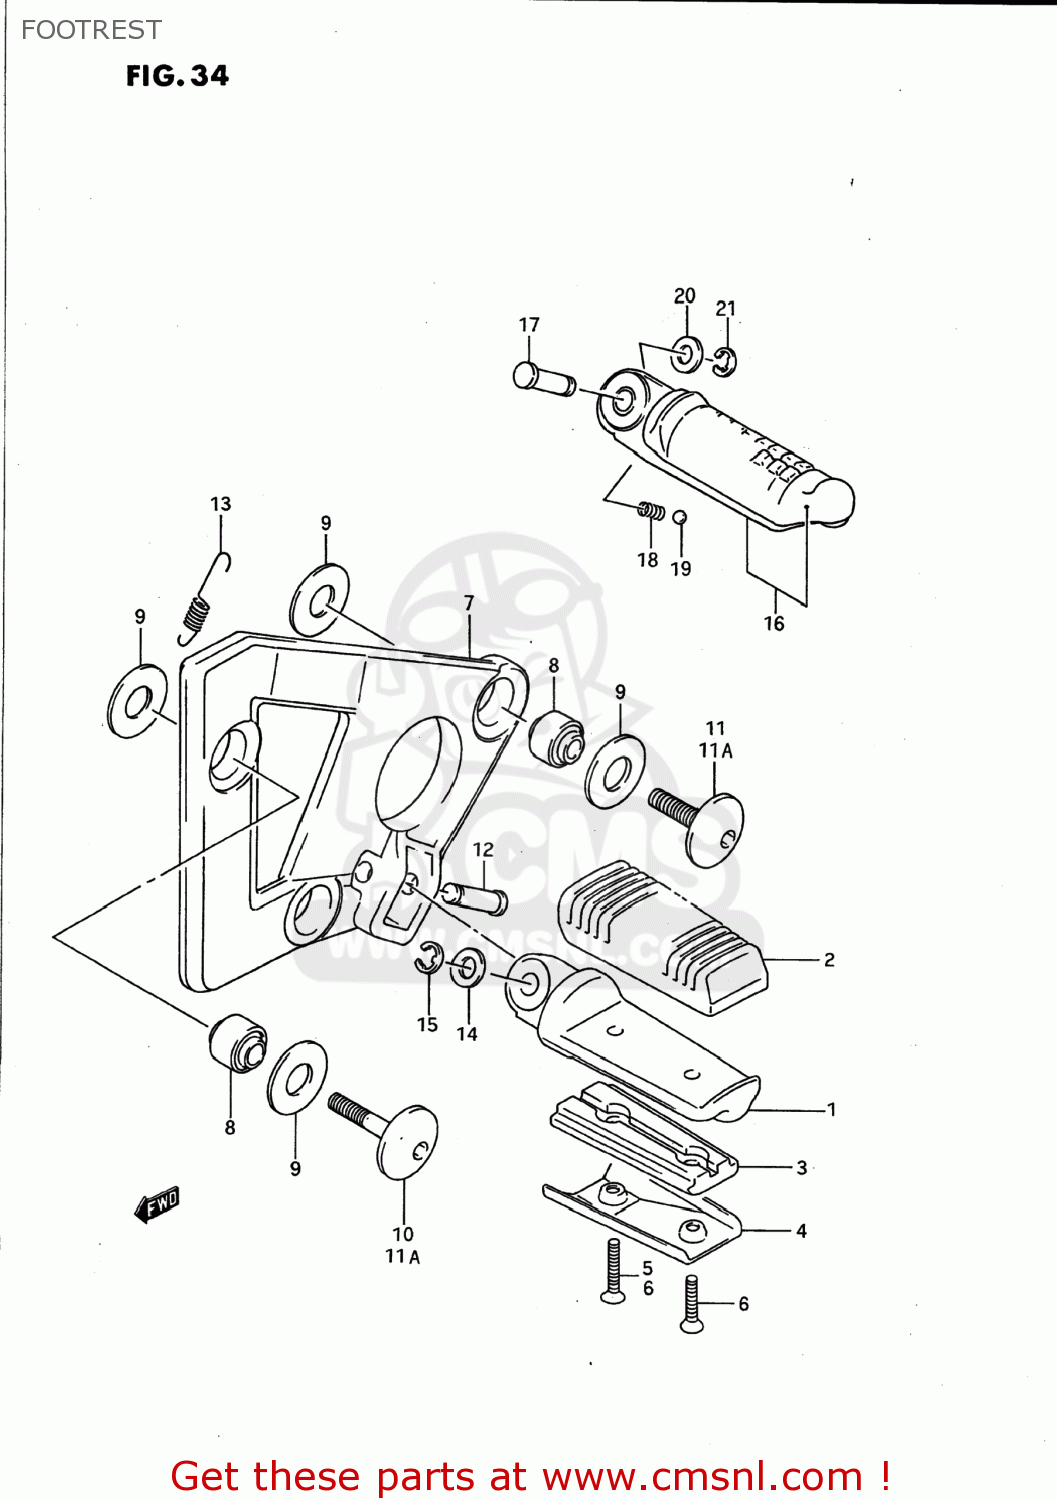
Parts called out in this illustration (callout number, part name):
1	BAR,FR FOOTREST,R
2	RUBBER,FR FOOTREST
3	BAR,FRONT FOOTREST NO
4	COVER,FOOTREST BAR
5	SCREW
6	SCREW
7	HOLDER,FRONT FOOTREST
8	BUSH(12X20X16)
9	WASHER (12X24X1.7)
10	BOLT L:30
11	BOLT(8X25)
11A	BOLT L:30
12	PIN
13	SPRING
14	WASHER
15	E.RING
16	BAR,PILLION FOOTREST,LEFT
17	PIN
18	SPRING
19	BALL
20	WASHER
21	E.RING
